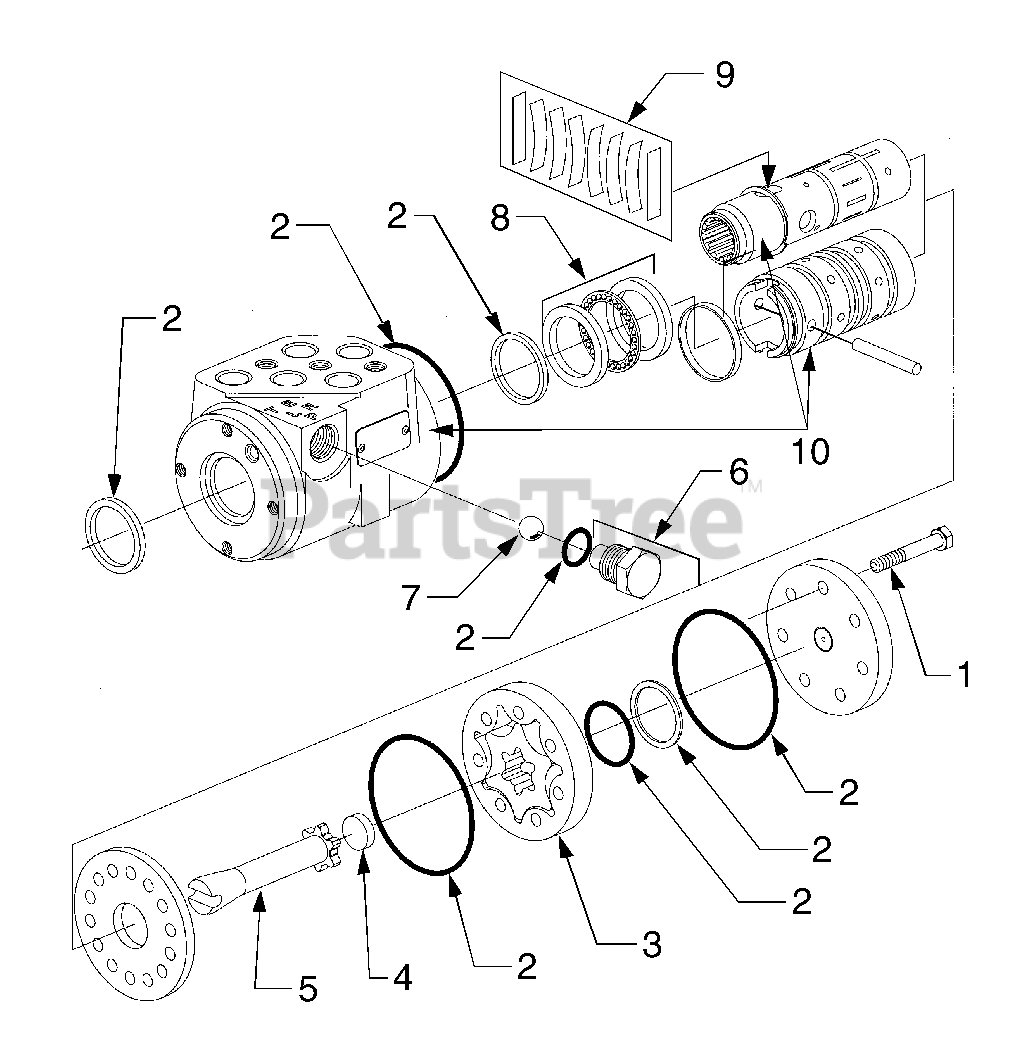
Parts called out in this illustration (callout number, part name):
1	Screw, Hex Cap, 1.57" Lg.
2	Seal Kit
3	Gerotor Assembly
4	Spacer, .240 Lg.
6	Plug, Manual Check
7	Ball, Manual Check
9	Spring Kit, Centering
10	Spool, Sleeve and Housing
